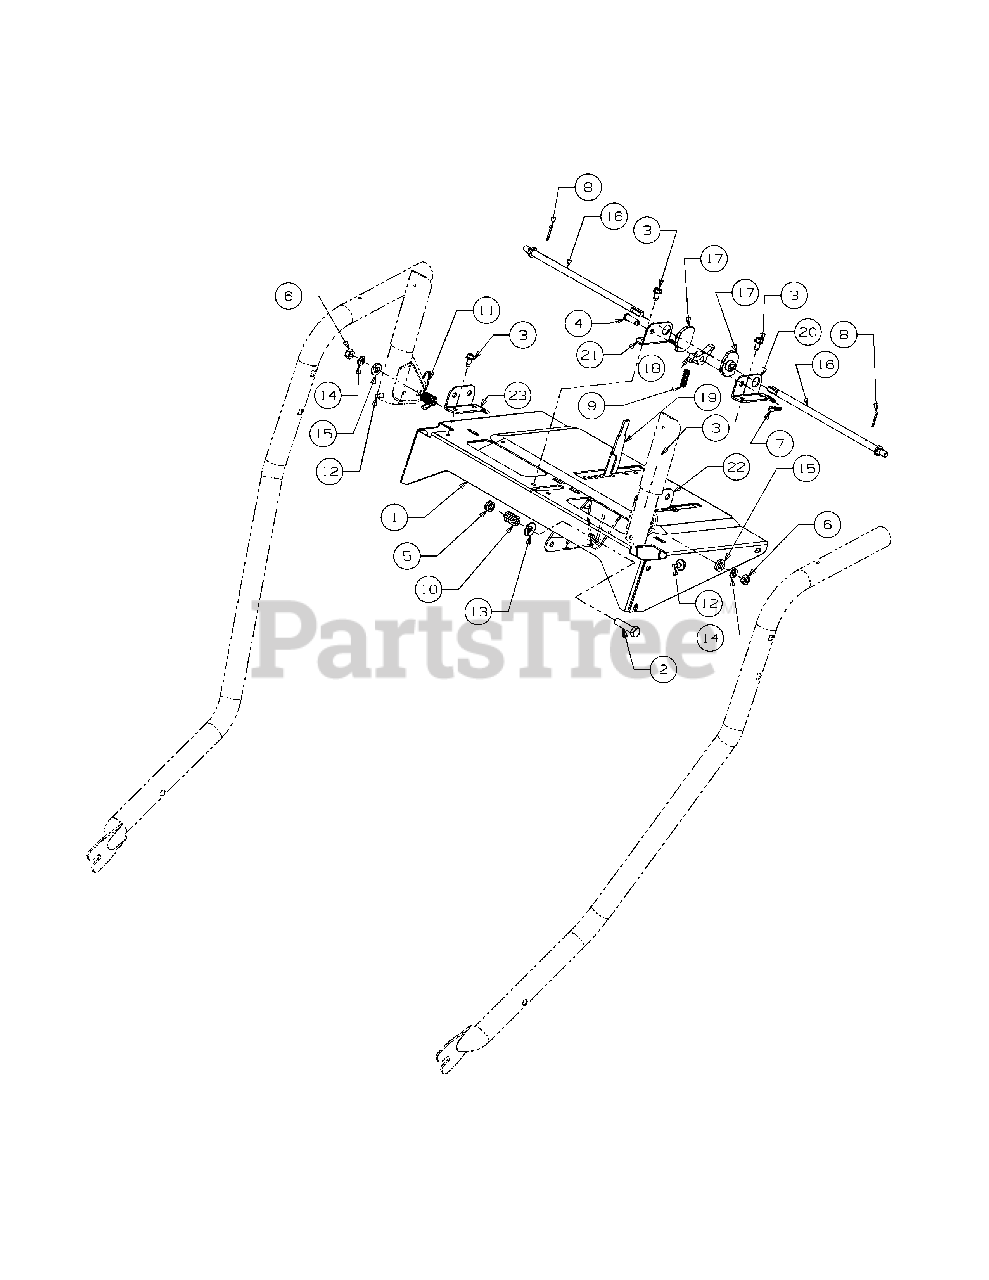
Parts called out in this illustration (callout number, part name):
1	Handle Panel Support Ass’y
2	Screw-Hex 3/8-16 X
3	Scr:Tt:L/4-20:0.500:Hxindwsh
4	Pin-Clevis
5	Nut-Top Lock
6	Nut-Hex Center L
7	Pin:Cot:.072 Dia
8	Pin-Cotter-3/32
9	Spring-Compression
10	Spring-Compression
11	Spring-Return
12	Rubber Bumper
13	Wash1Spr1 .401 X .870 X .083
14	Washer-Lock 5/16
15	Washer-Spec
16	Cam-Rod
17	Handle-Lockcam
18	Pawl-Handle Lock
19	Hndl:Shft:S/T
20	Brkt:Hndl Supt:S/B:Lh
21	Bracket-Handle
23	Bracket-Handle
